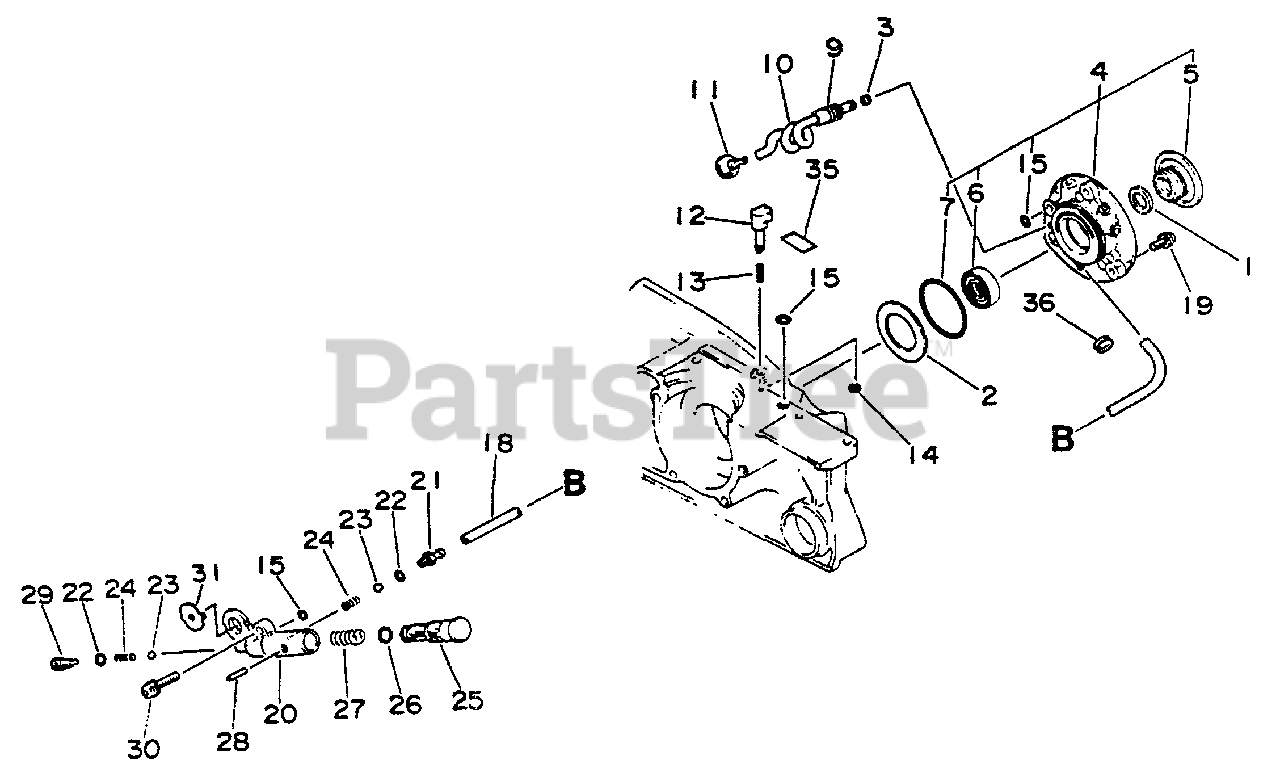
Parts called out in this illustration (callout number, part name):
2	PLATE
3	CLIP - 6.6
4	AUTO-OILER ASSY
5	WHEEL, WORM
6	SEAL, OIL
7	O-RING
10	PIPE, FUEL - SPIRAL
11	FILTER, OIL
12	DIAL, AUTO-OILER
14	RING, RETAINING - 3
15	O-RING - 3
18	PIPE - OIL
19	SCREW - 4X10
20	BODY, OIL PUMP
23	VALVE, BALL
24	SPRING, VALVE
25	PISTON, OIL PUMP
26	O-RING - 7
28	PIN - SPRING -- 2X16
29	ADAPTER, OIL PUMP
30	SCREW - 5X20
31	BRACKET, OIL PUMP
35	LABEL - CAUTION
36	CLIP - 6.6
